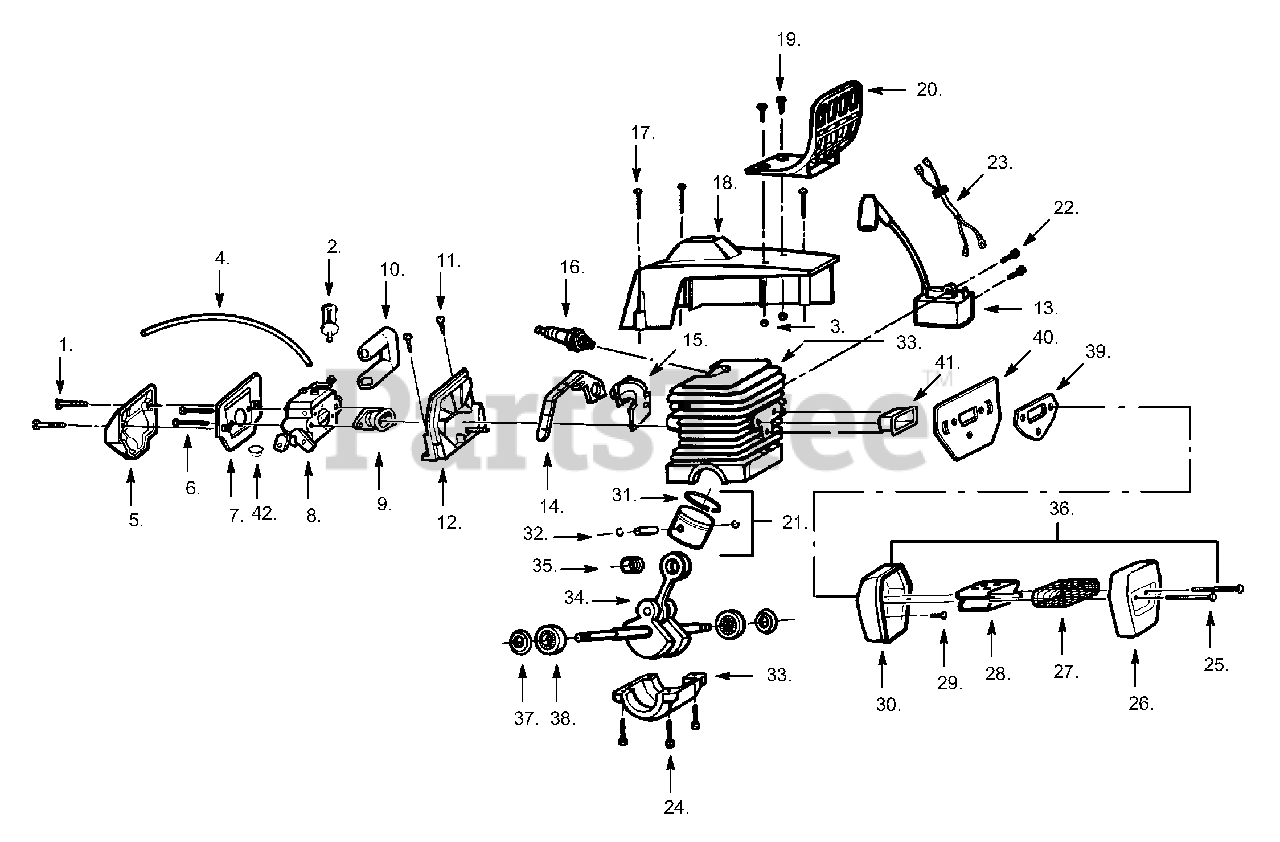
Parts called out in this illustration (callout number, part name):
2	Fuel Pick-up
4	Fuel Line
5	Air Filter (Top)
7	Air Filter (Bottom)
8	Carburetor
9	Intake Boot
10	Carb. Grommet
11	Screw
12	Carb. Adaptor
13	Ignition Module
14	Turbo Clean Seal
15	Turbo Air Cleaner Ass'y.
16	Spark Plug (CJ-7Y)
17	Screw
18	Cylinder Shield
20	Handguard
21	Piston Kit
23	Switch Wire Ass'y.
25	Muffler Bolt 5mm
25	Muffler Bolt 6mm
26	Muffler Cover
27	Spark Screen
28	Diffuser
30	Muffler Body
31	Piston Ring
32	Piston Pin Retainer
33	C'case & Cylinder Assy
34	C'shaft & Rod Ass'y.
35	Piston Pin Bearing
36	Muffler Kit
37	C'shaft Seal
38	C'shaft Bearing
39	Muffler Gasket
40	Muffler Plate
41	Heat Insulator
42	Isolator
